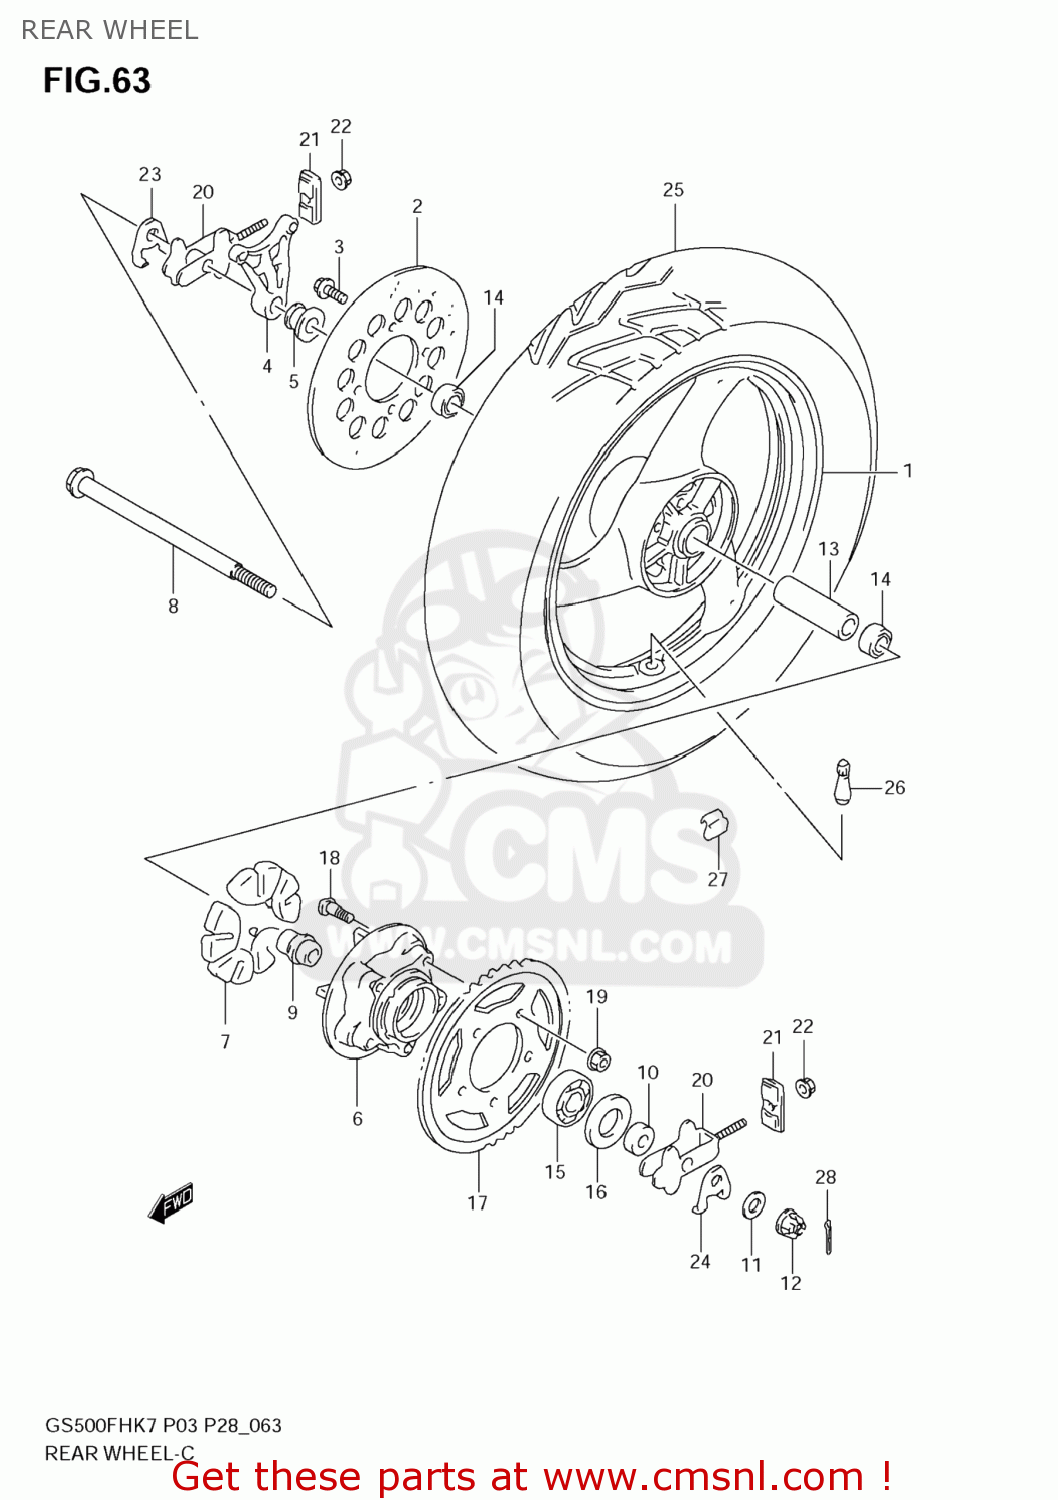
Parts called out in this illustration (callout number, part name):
1	WHEEL,RR(MT3.50X17)
2	DISC REAR BRAK
3	BOLT(8X30)
4	BRACKET,CALIPE
5	SPACER, REAR AXLE RH
6	DRUM, REAR SPROCKET
7	ABSORBER,RR HUB SHOCK
8	AXLE,RR
9	RETAINER, DRUM
10	SPACER, REAR AXLE LH
11	WASHER(17X30X3)
12	NUT
13	SPACER(17.5X25X88)
14	BEARING
15	BEARING(25X62X17)
16	SEAL,OIL(35X62X8)
17	SPROCKET, REAR (NT:39)
18	BOLT
19	NUT
20	ADJUSTER, CHAIN
21	PLATE, GUIDE
22	NUT
23	WASHER,CHAIN A
24	WASHER, CHAIN ADJUSTER LH
25	TIRE, REAR (130/70-17M/C 62H)
26	VALVE
27	BALANCER,WHEEL(10G)
28	PIN
